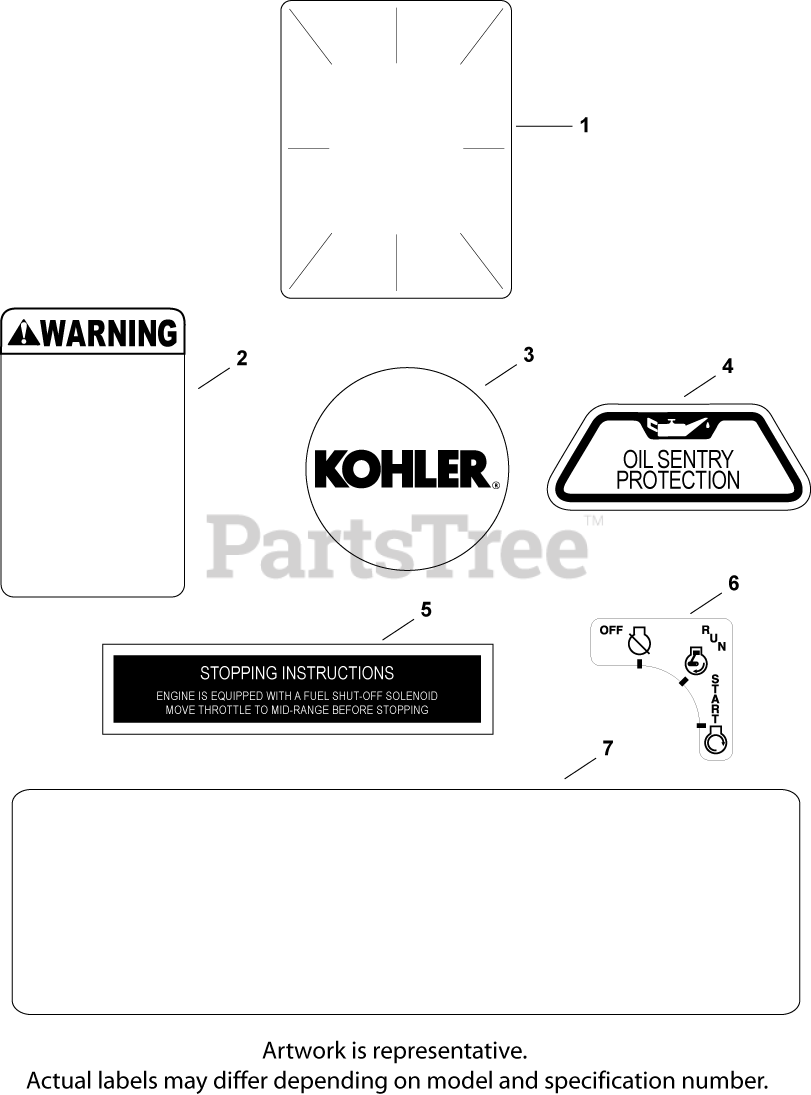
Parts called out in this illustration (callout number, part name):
1	DECAL, CLEAR LAMINATE USE 25 113 70-S
2	DECAL, CO WARNING
3	LABEL, (ROUND KOHLER GOLD)-USE 24 113 18
4	DECAL, OIL SENTRY - (#DSC)
5	DECAL, STOPPING INSTRUCTION
6	DECAL, KEY SWITCH
7	DECAL, 20 HP
